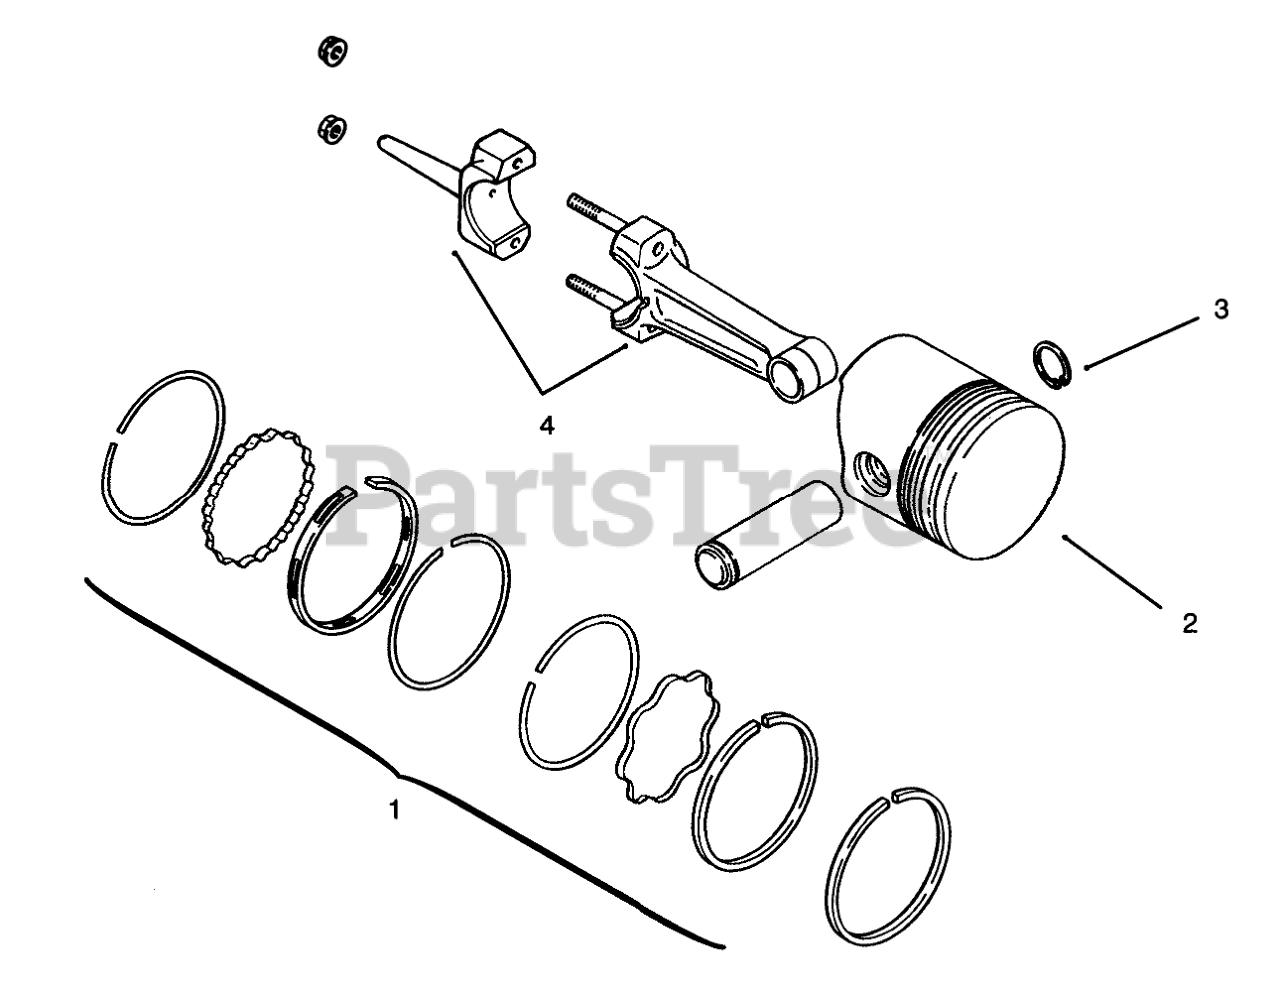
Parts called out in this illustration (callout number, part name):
1	Set-Ring, Std. &.003
2	Piston w/Ring Set Std.
3	Piston Pin Retainer
4	Rod-Connecting Std.
